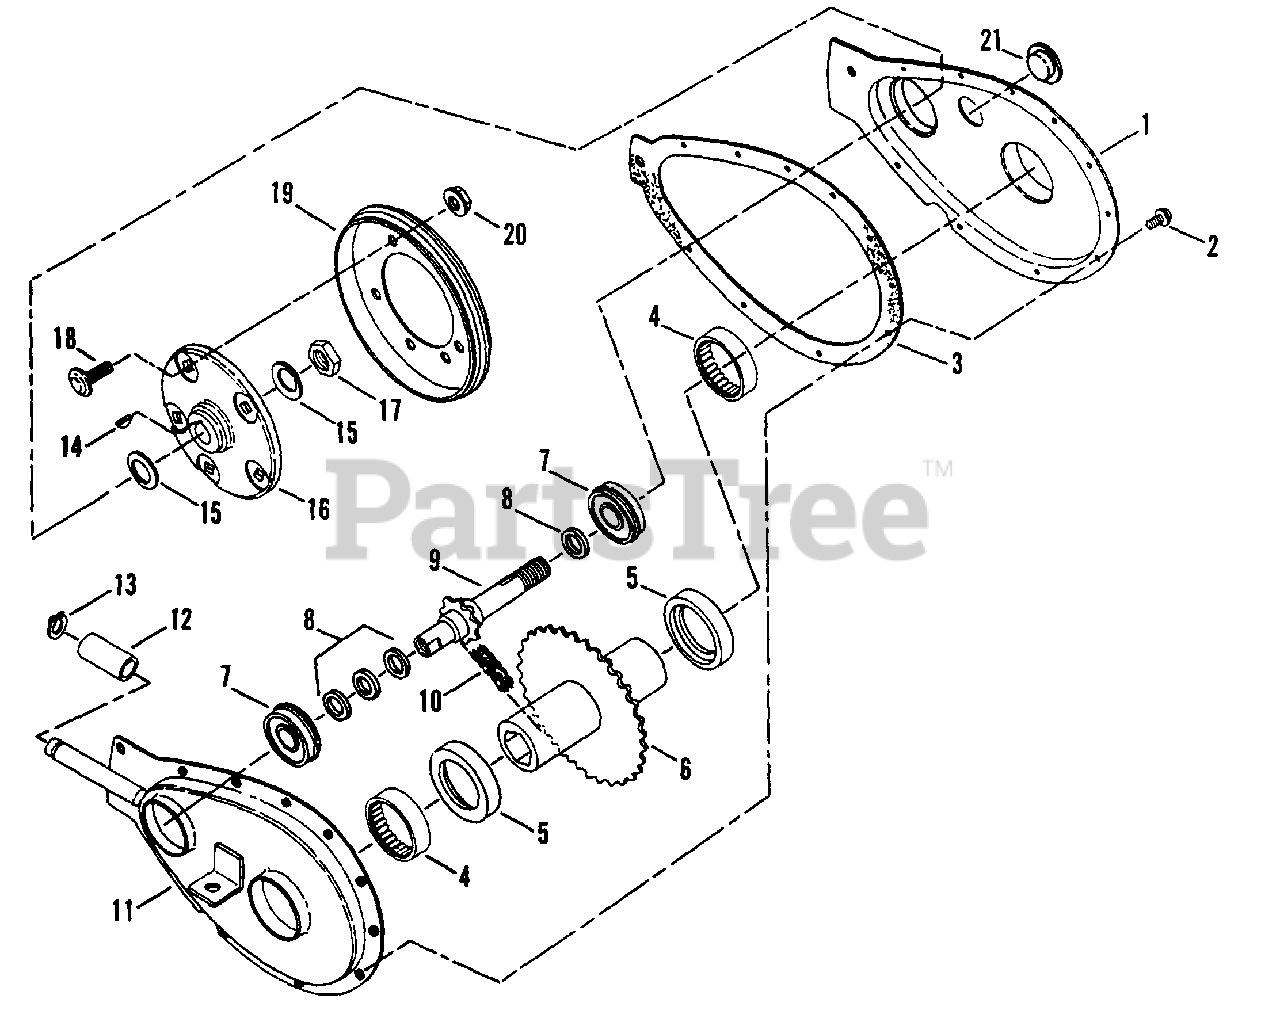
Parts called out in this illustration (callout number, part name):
1	COVER (Left Hand)
2	SCREW, #10-24 x 1/2" Hex Washer Self-Tap (Torx)
3	GASKET
4	BEARING, Needle 1.355" ID x 1.6245" OD x .5" Wide
5	WASHER, Thrust
6	HUB SPROCKET
7	BEARING, Ball 5/8" ID x 1-3/8" OD
8	WASHER, Shim
9	SPROCKET - SHAFT
10	CHAIN, 46 Pitch (#35 Endless)
11	SPROCKET CASE (Right Hand)
12	ROLLER
13	RING, Retaining 1/2"
14	KEY, Woodruff
15	WASHER, Belleville .64 x 1.125 x .028
16	HUB
17	NUT, 5/16-18 Hex Center-Lock
18	BOLT, 5/16-18 x 1/2" Short Neck Carriage, Grade 5
19	DISC, Driven
20	NUT, 5/16-18 Hex Flange Lock
21	PLUG, 3/4"
